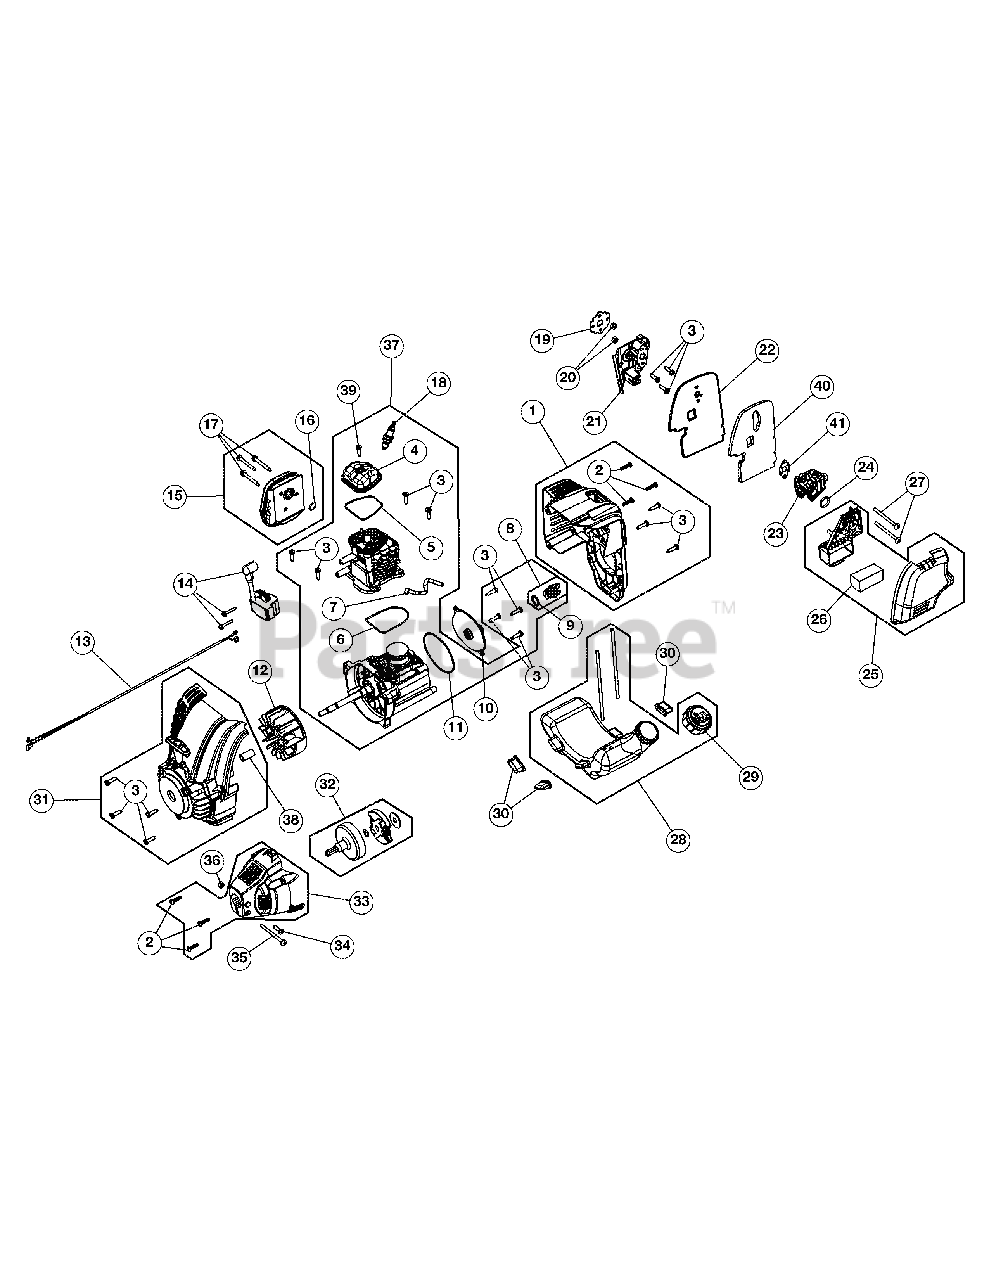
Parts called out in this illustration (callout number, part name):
1	Engine Cover Assembly (Incl. 2 & 3)
2	Cover Screw
3	Screw
4	Rocker Cover
5	Rocker Cover O-Ring
6	Cylinder O-Ring
7	Breather Hose
8	Oil Plug (Incl. 9)
9	Oil Plug O-Ring
10	Crankcase Cover
11	Crankcase Cover O-ring
12	Flywheel Assembly
13	Lead Wires
14	Module Assembly
15	Muffler Assembly (Incl. 16 & 17)
16	Muffler Gasket
17	Muffler Screw
18	Spark Plug
19	Insulator Gasket
21	Insulator
22	Carburetor Gasket
23	Carburetor w/Primer
24	Air Cleaner O-Ring
25	Air Cleaner Cover Assembly (Incl. 26)
26	Air Filter
28	Fuel Tank Assembly w/Fuel Lines (Incl. 29)
29	Fuel Cap
30	Fuel Tank Pads
31	Starter Housing Assembly (Incl. 3 & 38)
32	Clutch Assembly
33	Clutch Cover (Incl. 2)
34	Anti-Rotation Screw
35	Clamp Screw
37	Shortblock Assembly
38	Spacer
39	Rocker Cover Screw
40	Heat Shield
